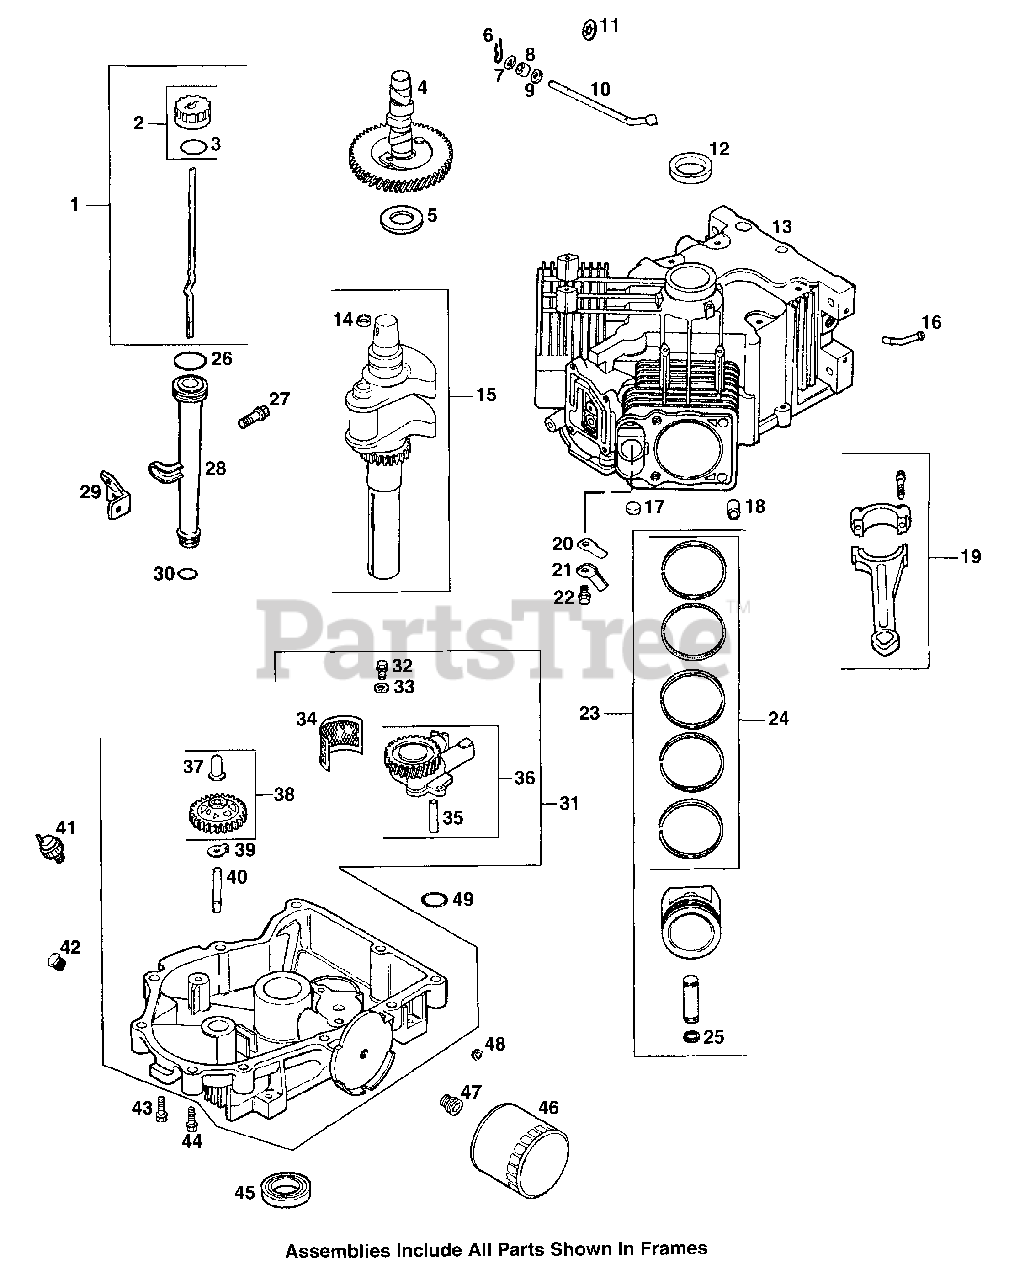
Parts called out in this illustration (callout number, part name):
1	Dipstick Assembly
2	Oil Fill Cap Kit
3	Dipstick O-Ring
4	Camshaft
5	Camshaft Shim (A.R.)
6	Hitch Pin
7	Washer 6mm
8	Seal
9	Washer, 1/4"
10	Gov. Shaft
11	Retainer Ring
12	Front Oil Seal
13	Crankcase
14	Cup Plug (Crankshaft)
15	Crankshaft
17	Cup Plug
18	Locating Pin
19	Connecting Rod (Std)
20	Breather Reed
21	Reed Retainer
22	Hex Flange Screw, M5 x .8 x 10
23	Piston w/ Ring Set (Std)
24	Ring Set (Std)
25	Piston Pin Retainer
26	Upper Oil Fill Tube O-Ring
27	Hex Flange Screw, M5 x.8 x 16
28	Oil Fill Tube
29	Oil Fill Tube Bracket
30	Lower Oil Fill Tube O-Ring
31	Oil Pan Assembly
32	Hex Flange Screw, M6 x 1.0 x 25
33	Washer, 6mm
35	Oil Pickup Tube
36	Oil Pump Assembly
37	Governor Regulating Pin
38	Governor Gear Kit
39	Locking Tab
40	Governor Gear Shaft
41	Pressure Switch
42	Hex Head Plug, 3/8"
43	Hex Flange Screw, M8 x 1.25 x 45
44	Hex Flange Screw, M8 x 1.25 x 45
45	Oil Seal, PTO Side
46	Oil Filter
47	Oil Filter Nipple
48	Hex Countersunk Plug, 3/8"
